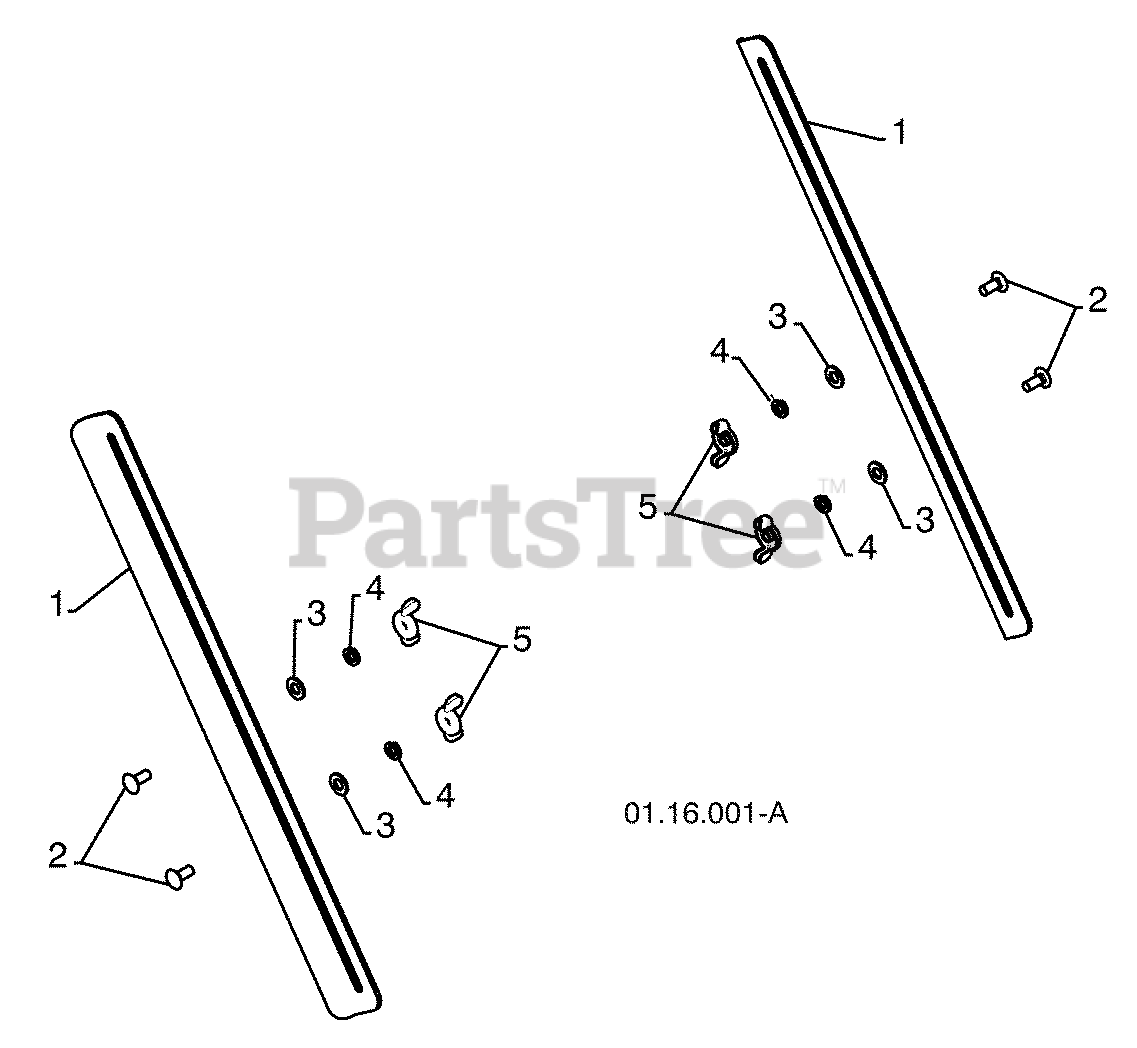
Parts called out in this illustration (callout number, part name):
1	DRIFT CUTTER BAR
2	CARRIAGE BOLT 5/16-18 X .750
3	PLASTIC WASHER
4	LOCKWASHER 5/16
5	NUT 5/16-18
